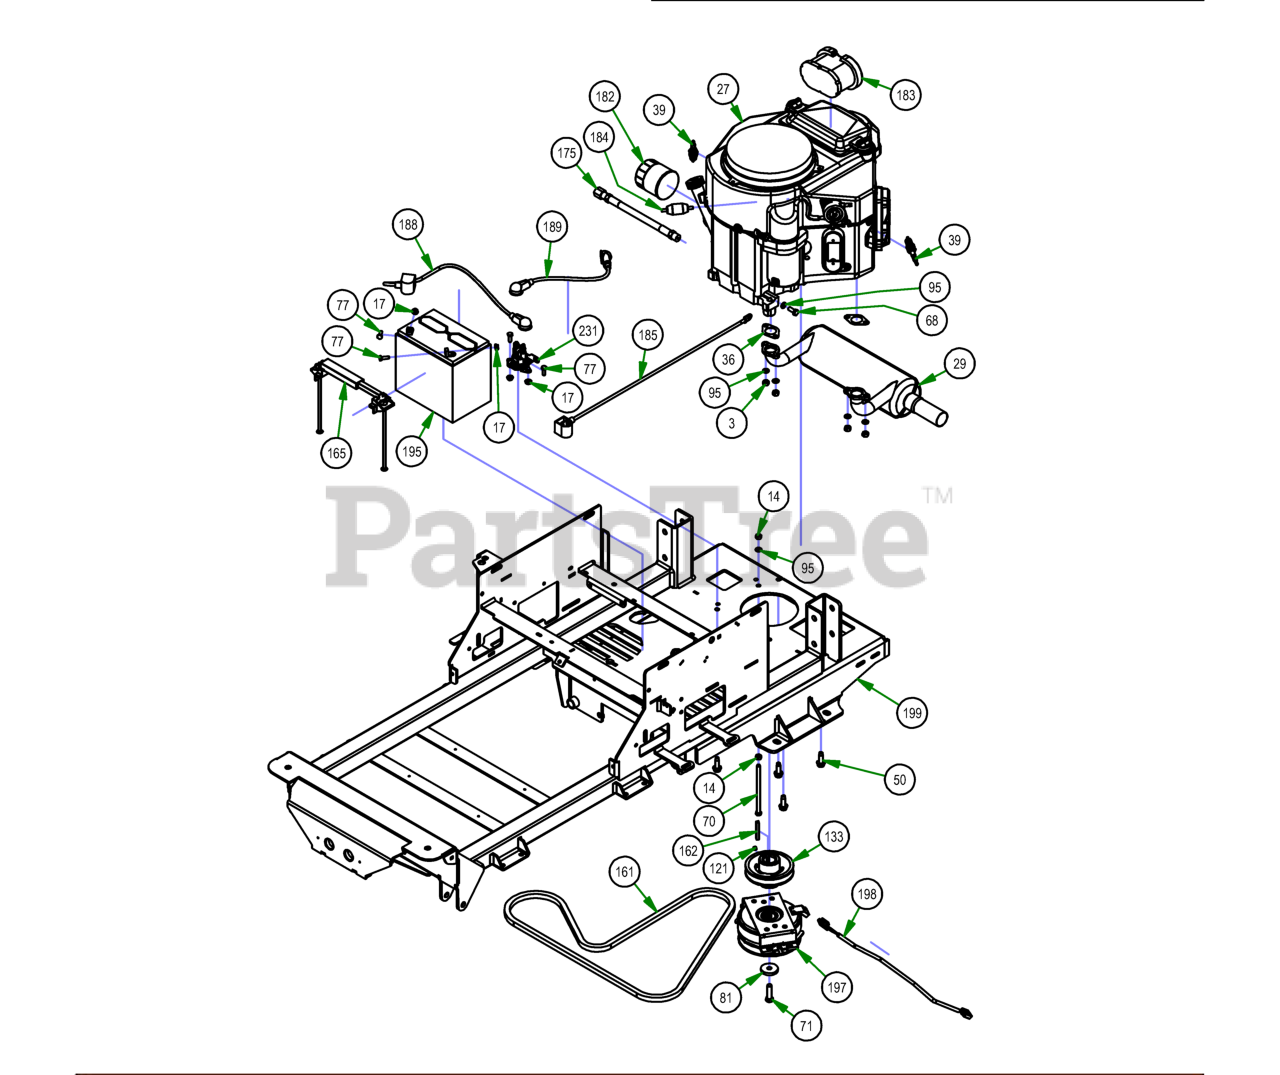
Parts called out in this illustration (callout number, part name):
3	M8-1.25 DIN 934 HEX NUT (CL.8) ZINC
14	5/16-18 HEX NUT ZINC
17	1/4-20 HEX SERRATED FLANGE NUT HARD/ZINC
27	FS730V Engine
29	Kawasaki Muffler 1251
36	Exhaust Gasket
39	Spark Plug - Kawasaki
50	3/8-16 X 1-1/8HEX WASHER UNSLOT SERRATED (TRI-LOB) TRS
68	M8-1.25 X 20MM DIN 933 HEX TAP BOLT (CL 8.8) ZINC
70	5/16-18 X 5-1/2 HEX CAP SCREW (GR.5) ZINC
71	7/16-20 X 1-1/2 HEX CAP SCREW (GR.8) ZINC YELLOW
77	1/4-20 X 3/4 HEX CAP SCREW (GR.5) ZINC
81	CLUTCH WASHER
95	5/16 SPLIT LOCKWASHER ZINC
121	5/16-24 X 1/4 SOCKET SET SCREW (CUP PT) PLAIN
133	4 3/4 Motor Pulley
161	75.8" Pump Belt
162	1/4 X 2 SQ MACHINERY KEY 1018 STL PLAIN
165	Hold Down Assembly
175	Oil drain Hose
182	22-26 Kaw Oil Filter FR Engine
183	Kawasaki Air Filter
184	Universal Inline Fuel Filter
185	24 inch Black Cable – MZ/ZT
188	24" Red Battery Cable
189	12" Red Battery Cable
195	SP-35 Battery
198	Clutch Pigtail
199	2021 Maverick Frame - Painted
213	Patent Decal
